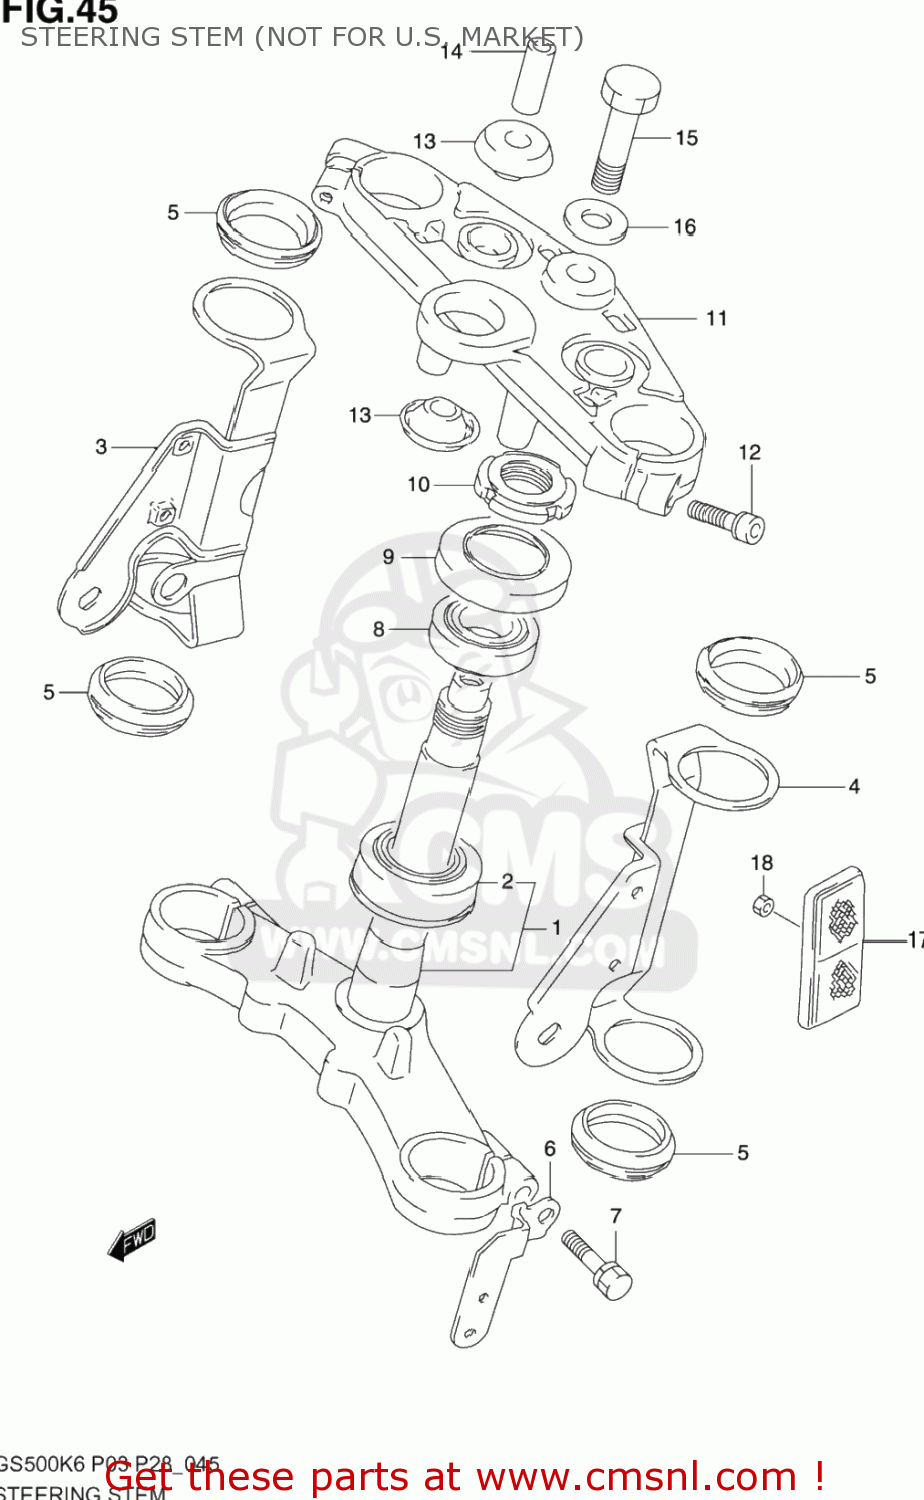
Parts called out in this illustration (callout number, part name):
1	STEM, STEERING
2	BEARING(30X55X17)
3	BRACKET, HEADL
4	BRACKET,HEADLA
5	CUSHION,HEADLAMP BRACKET
6	BOLT,STEERING
7	BEARING(25X47X15)
8	SEAL,STEERING UPR DUST
9	NUT,STEERING STEM(25X44X10)
10	HEAD STEERING
11	BOLT
12	CUSHION, STEM HEAD
13	SPACER, HEAD S
14	BOLT, UPPER
15	WASHER
